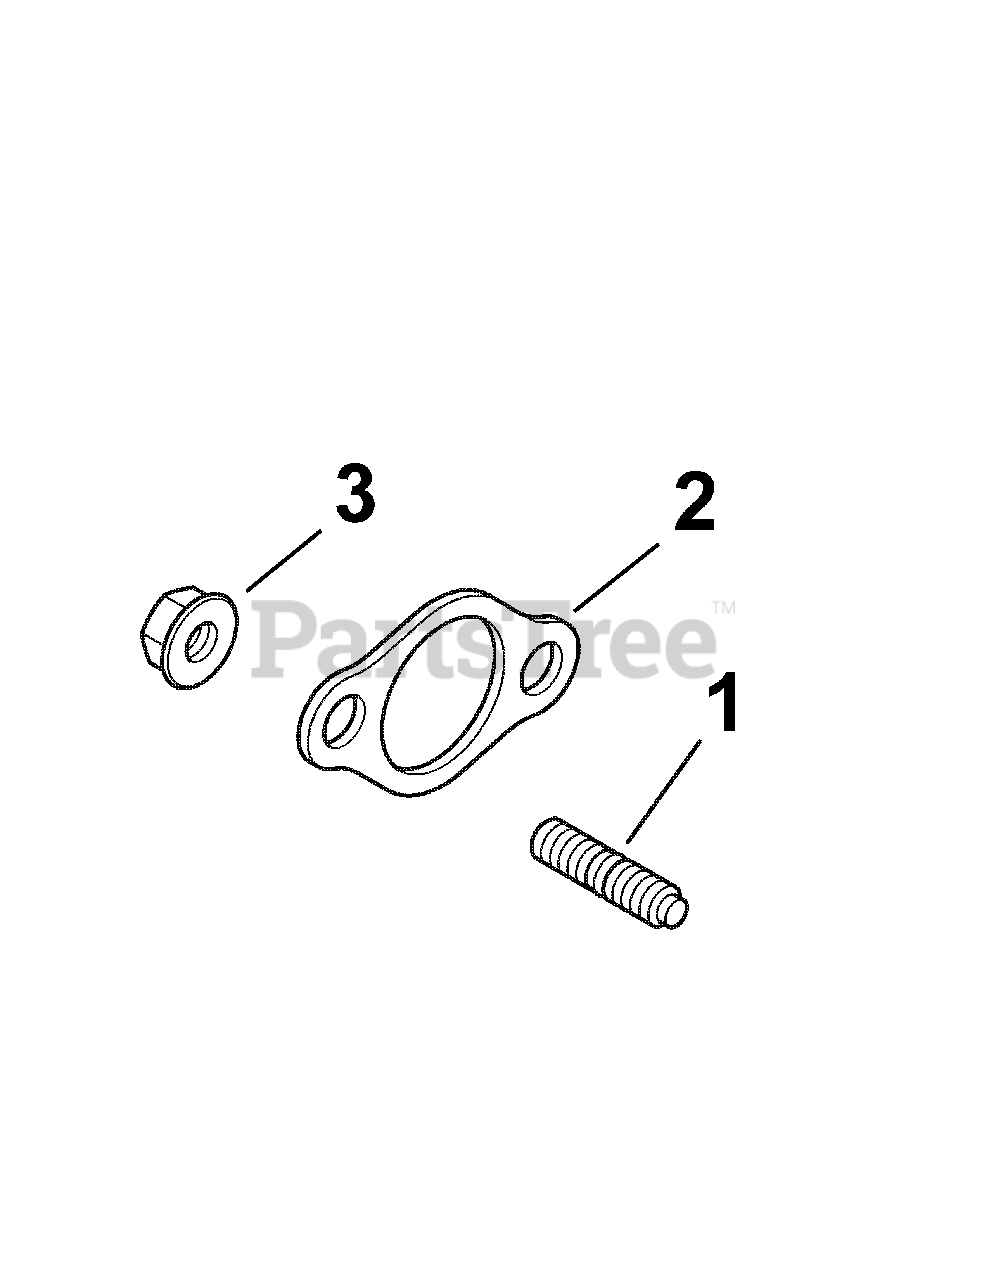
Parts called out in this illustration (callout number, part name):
1	Stud, M8 x 1.25 x 33
2	Gasket, Exhaust
3	Nut, Flg, M8 x 1.25
